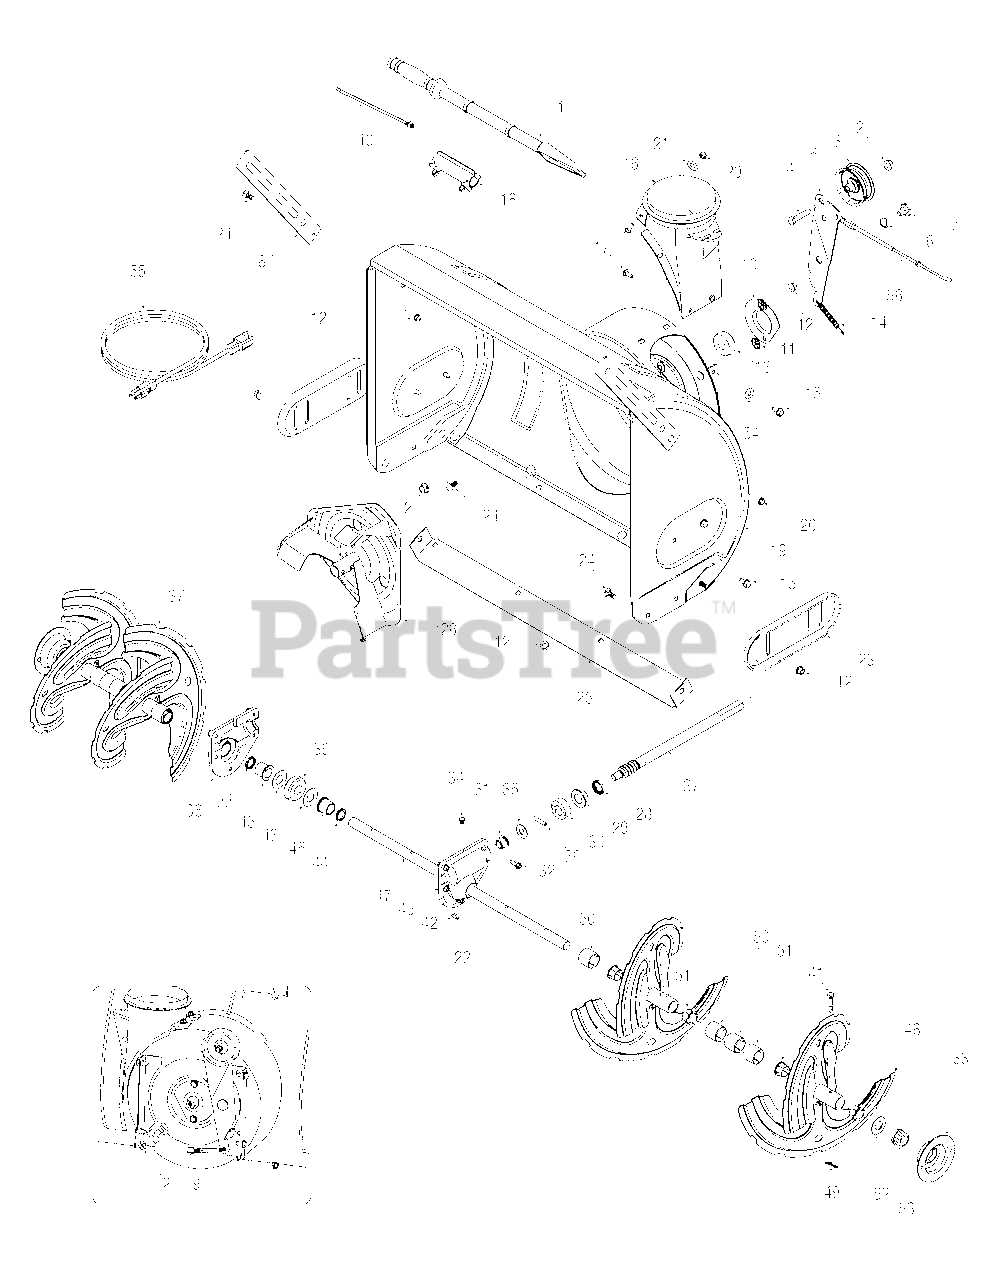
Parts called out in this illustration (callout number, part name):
1	Clean-Out Tool
2	Flange Lock Nut
3	Flat Idler Pulley
4	Hex Bolt, 3/8-16 x 1.75
6	Wave Washer
7	Shoulder Screw
9	Shoulder Screw
10	Bearing Housing
11	Push Nut
12	Flange Lock Nut, 5/16-18
13	Ball Bearing
14	Extension Spring
15	AB Screw, 5/16-18 x 0.625
16	Chute Adapter
17	Carriage Screw, 1/4-20 x 0.
18	Clean-out Tool Mtg. Bracket
20	Flange Lock Nut, 1/4-20
21	Flat Washer
22	Gearbox Assembly Complete
24	Carriage Bolt
27	Worm Shaft
28	Oil Seal
29	Flange Bearing
30	Thrust Collar
31	Flange Bearing
32	TT Screw, 1/4-20 x 0.75
35	Flat Washer
36	Dowel Pin
38	Reducer Hsg.-RH (Incl Ref. 44-45)
39	Worm Gear, 20T
40	Cable Tie
41	Shear Pin
42	Key
43	Flat Washer
44	Oil Seal
45	Flange Bearing
46	Reducer Hsg.-LH (Incl Ref. 44-45)
47	Auger Axle
49	Bow Tie Cotter Pin
50	Spacer
51	Flange Bushing
52	Flat Washer
53	Hex Flange Bearing
54	Bell Washer
55	Extension Cord
56	Auger Clutch Cable
